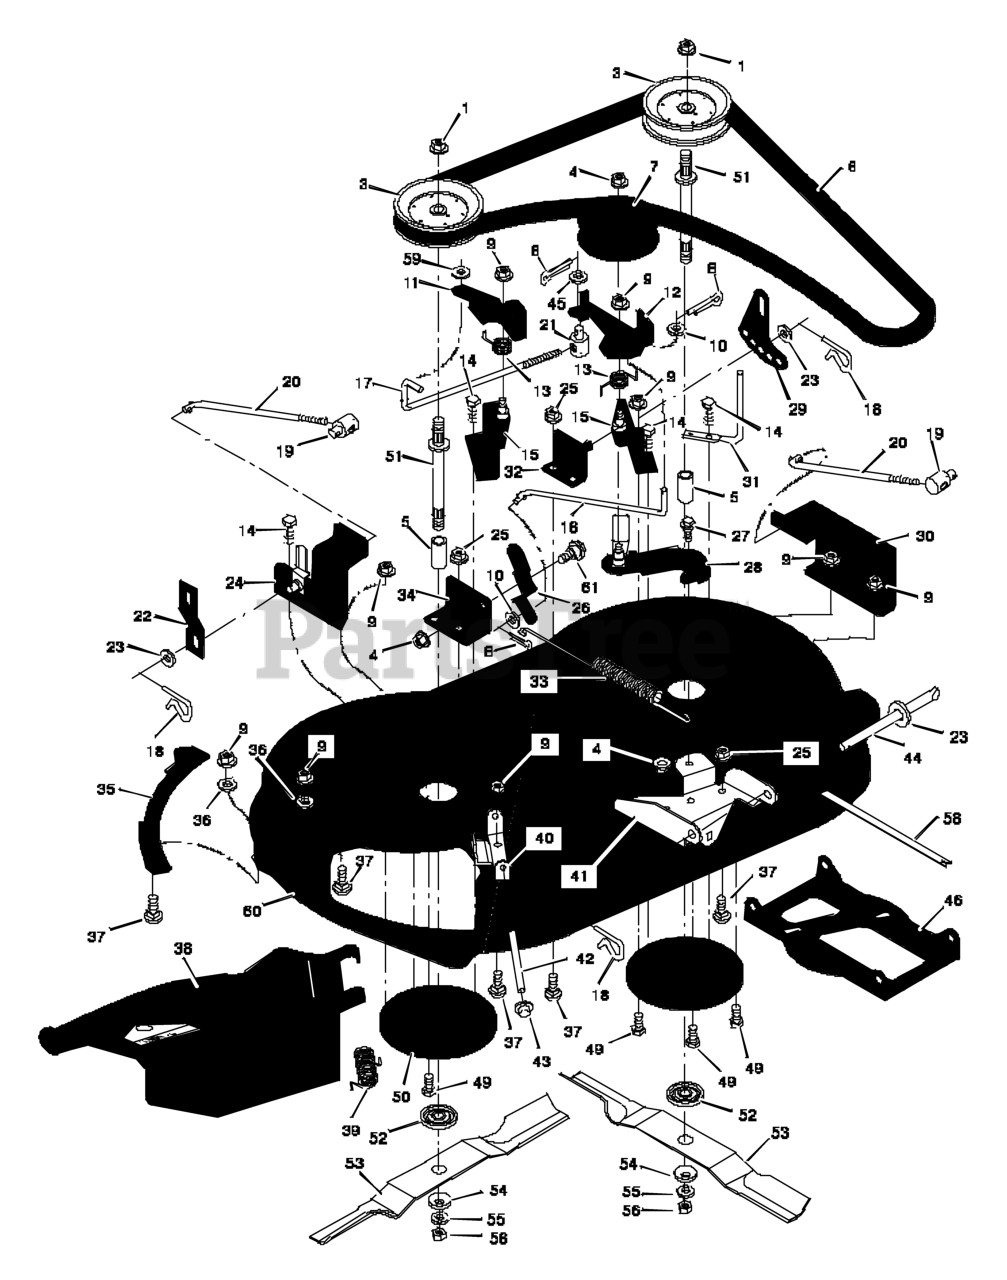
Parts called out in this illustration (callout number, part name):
1	Nut, Hex
3	Pulley, Jackshaft
4	Locknut, Flange
5	Spacer
6	Belt, Blade Drive
7	Pulley, Idler
8	Pin, Cotter
9	Locknut, Flange
11	Brake Assembly, Right
12	Brake Assembly, Left
13	Spring, Torsion
14	Bolt, Hex
15	Bracket Assembly, Brake
16	Rod, Brake
17	Rod, Cross Link
18	Pin, Hair
19	Nut, Adjustable
20	Rod, Adjuster
21	Nut, Adjustable
22	Link, Suspension
24	Bracket Assembly, Right Lifter
25	Nut, Flange
26	Bracket, Pivot
27	Bolt, Shoulder
28	Arm Assembly, Idler
29	Plate, Adjuster
30	Cover, Pulley
31	Guide, Belt
32	Bracket Assembly, Left Lifter
33	Spring, Extension
34	Bracket, Pivot
35	Plate
37	Bolt, Carriage
38	Deflector Assembly, Chute
39	Spring, Torsion
40	Bracket, Hinge
41	Bracket, Front Hanger
42	Rod, Deflector
43	Cap, Push On
44	Rod, Hanger
46	Hanger, Front
49	CAPSCREW, Hex Head, 5/16-18 x 1
50	Housing, Jackshaft
51	Jackshaft
52	Adapter, Blade
53	Blade, 40" (2 required)
54	Washer, Belleville
56	Nut, Hex
58	Indicator, Plastic
60	Housing, Blade (40")
61	Bolt, Shoulder
